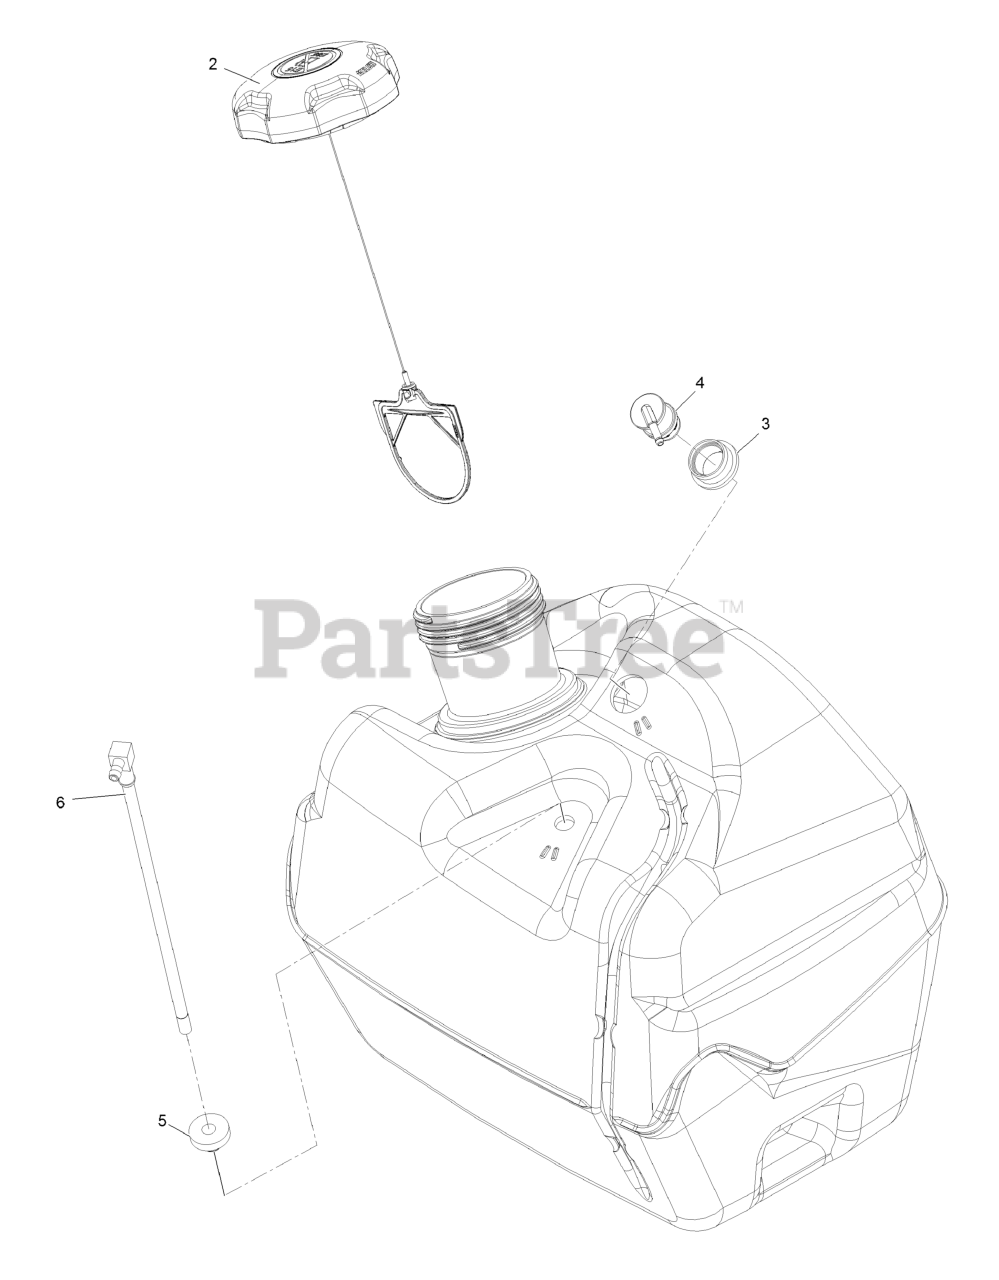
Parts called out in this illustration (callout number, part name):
2	CAP-FUEL, RATCHETING
3	GROMMET
4	VALVE-VENT, FUEL
5	BUSHING
6	FITTING, FUEL W/LINE AND SCREEN
